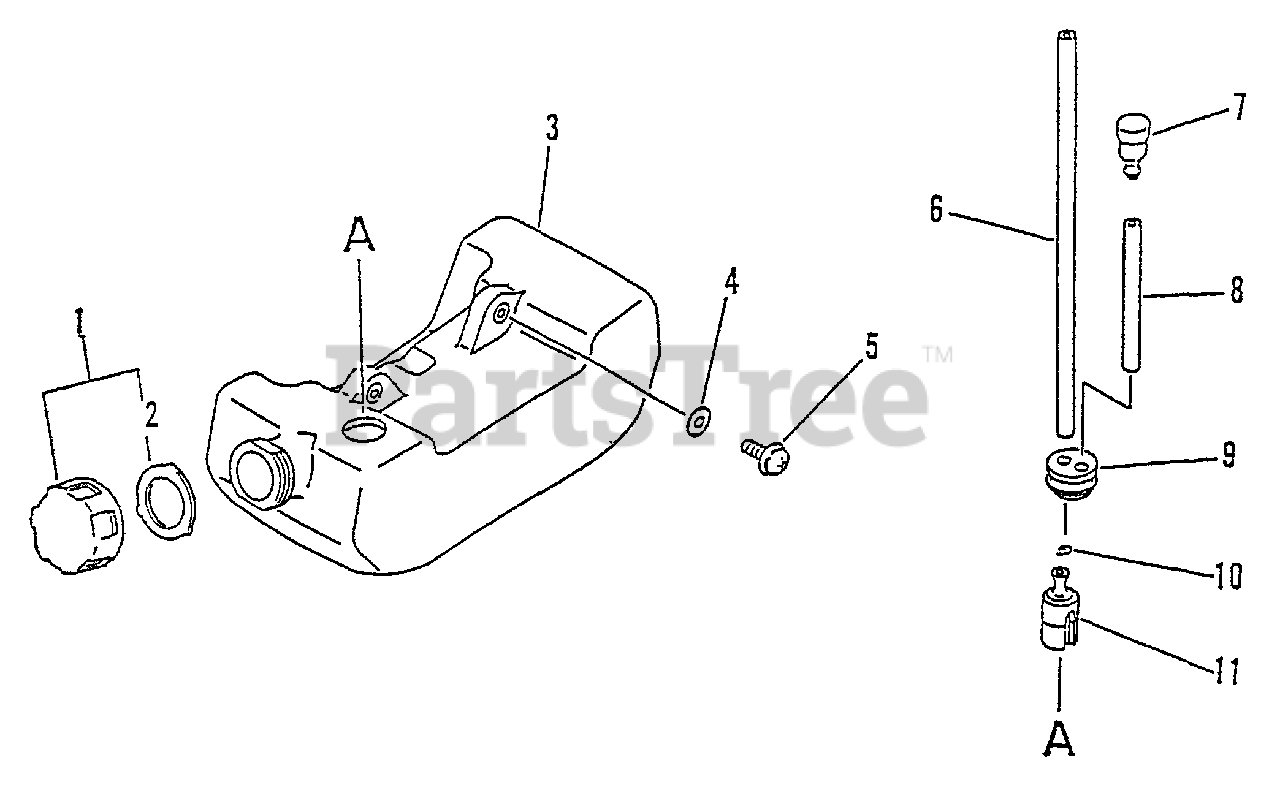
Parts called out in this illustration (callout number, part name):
1	CAP ASSY
2	GASKET, CAP
3	TANK, FUEL
4	WASHER - 5
5	SCREW - 5X16
6	PIPE - 3X5X180 -- BLACK
7	VENT, FUEL TANK
8	PIPE - 3X5X70 -- BLACK
9	GROMMET
10	CLIP - 6
11	FILTER, FUEL
